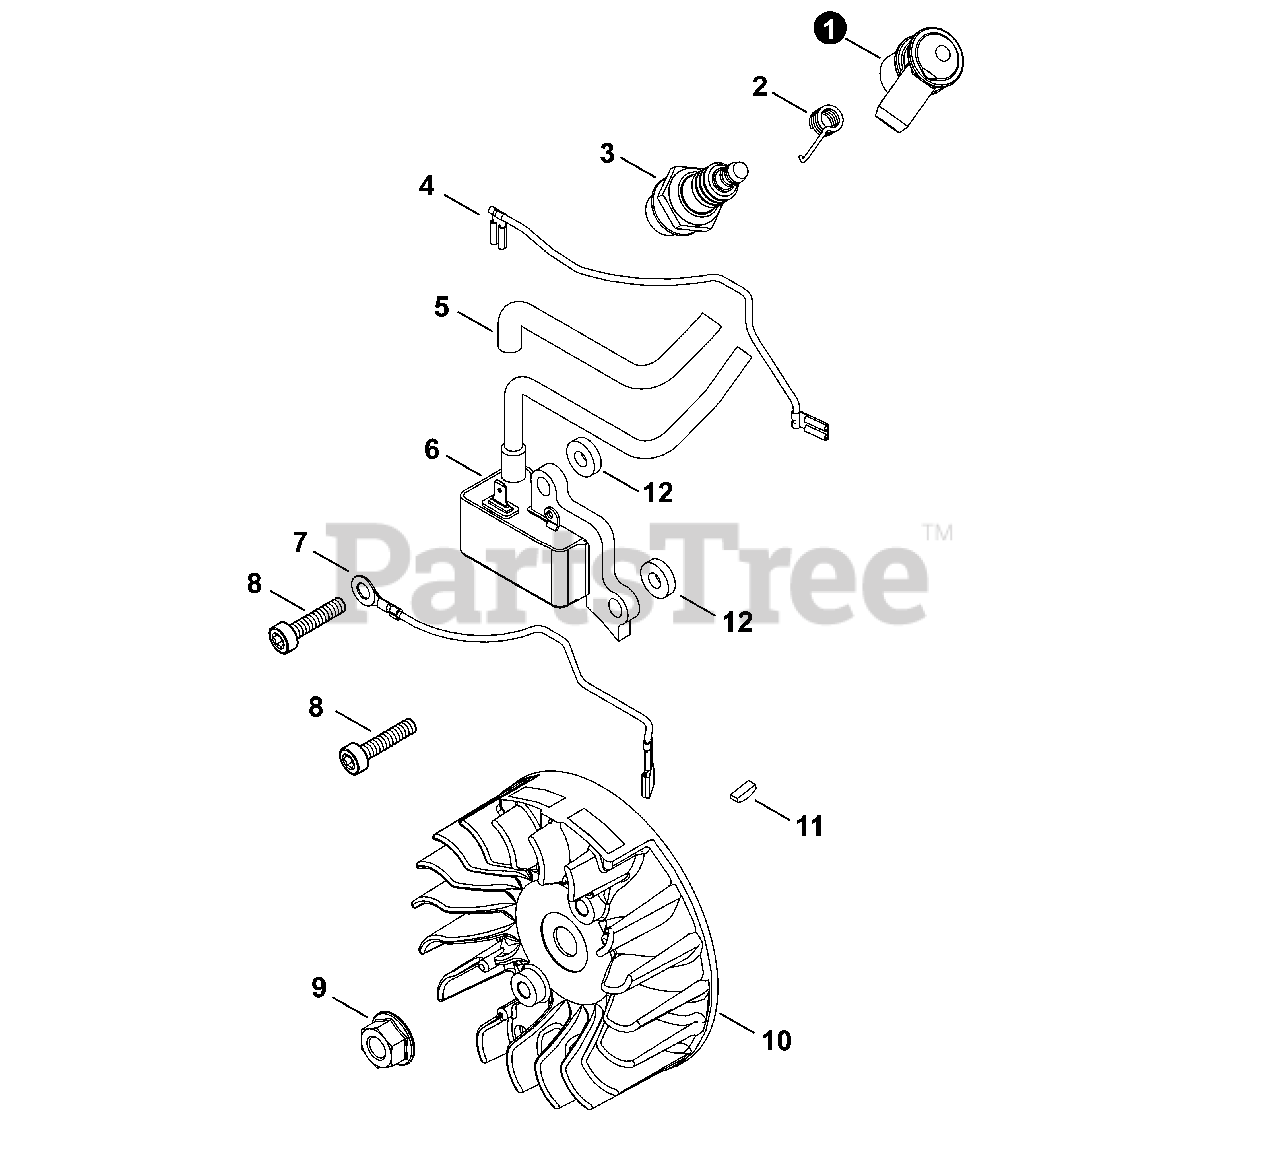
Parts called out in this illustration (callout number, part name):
1	CAP, SPARK PLUG
2	TERMINAL, SPARK PLUG
3	SPARK PLUG - BPMR8Y
6	COIL, IGNITION
8	BOLT, TORX 5×20
9	NUT, FLANGE M8
10	FLYWHEEL
11	KEY, WOODRUFF
12	WASHER 5.2×12×3
